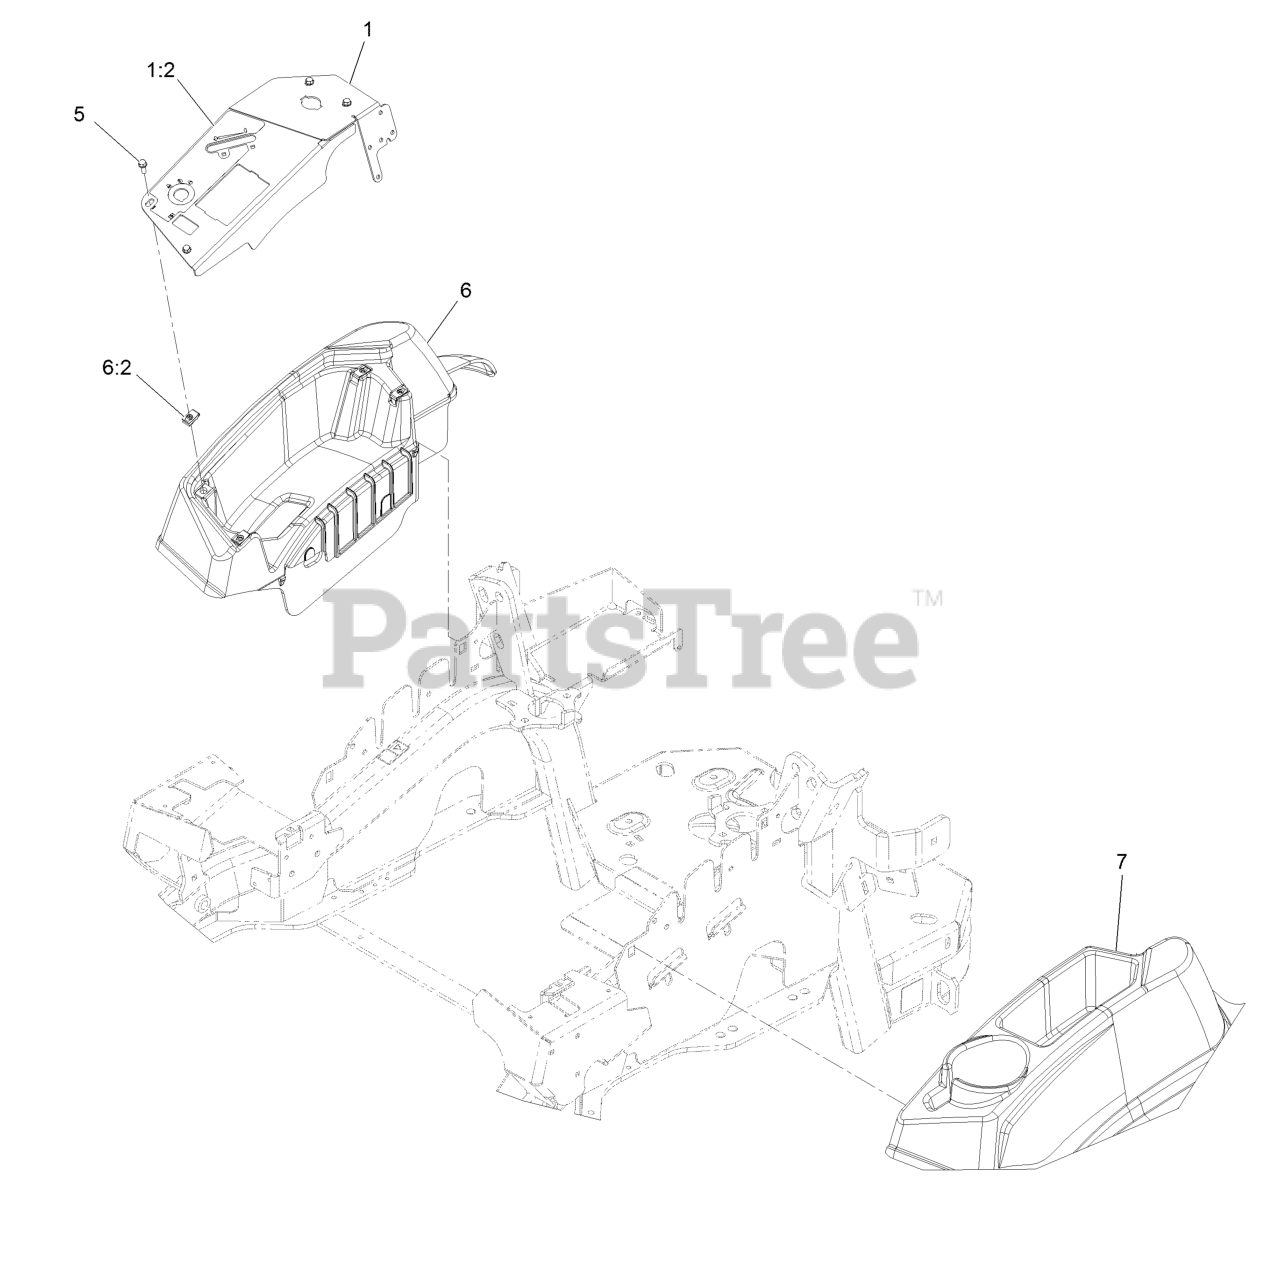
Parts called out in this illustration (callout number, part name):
1	Panel-Control W/Decal Shm-Efi
1:2	Decal-Control Panel-Efi
5	Screw-HWH
6	Console,RH As ASM
7	Console, LH As
